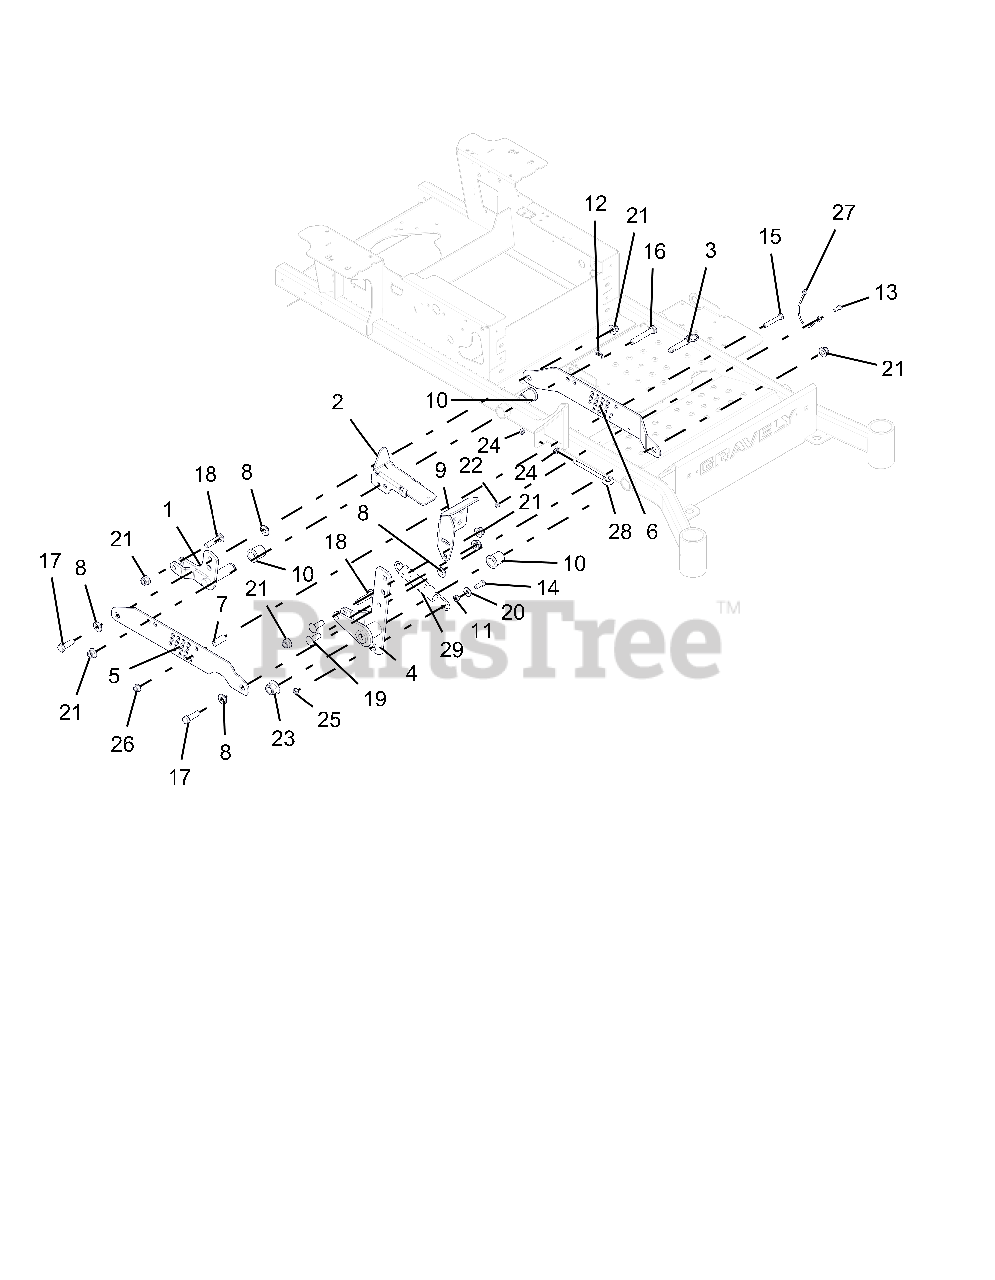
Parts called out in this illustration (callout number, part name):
1	WLDMT, RH REAR DECK LIFT
2	WLDMT, MECHANICAL LOCK-UP-BLACK
3	PIN, .500 x 2.000 USABLE LG BALL
4	WLDMT, TAPERED LIFT ARM FRONT LH-BLACK
5	BRKT, RH OUTBOARD LIFT/CUT HEIGHT-BLACK
6	BRKT, RH INBOARD LIFT/CUT HEIGHT-BLACK
7	SPACER, .375 X .625 X 1.54
8	BSHG, FLANGE .515X.750X.31X1.12
9	PEDAL, ADJUSTABLE FOOT LIFT
10	BSHG-FLG 1.00X1.25X1.5X1.5
11	BSHG, SLV .377X.624X.235
12	RG-RTNG-EXT 1.00X.078
13	BLT-HEX .25-20X.75 GR5 YWZC
14	BLT-HEX .38-16X1.00 GR5 YWZC
15	BLT-HEX .38-16X2.50 GR5 YWZC
16	BLT-HEX .50-13X3.25 GR5 YWZC
17	BLT-HEX .50-13X1.75 GR5 YWZC
18	BLT-RDHDSQNK .50-13X2.25 G5 Y
19	BLT-RDHDSQNK .50-13X1.50 G5 YWZC
20	WSHR-FL-STL.438X1.00X.083 YWZC
21	NUT-LK-NYL-FLG .50-13 YWZC
22	NUT-LK-NYL-FLG .25-20 YWZC
23	NUT-LK-NYL-FLG .75-10 YWZC
24	NUT, JAM .375-16 YWZC
25	@NUT-LK-CTR-JAM .375-16 YWZC
26	NUT-LK-NYL-FLG .38-16 YWZC
27	LANYARD, 12"
28	BOLT, EYE .38-16X6.00 .62 DIA
29	SPRG, TENSION .162 X 1.250 X 8.250
